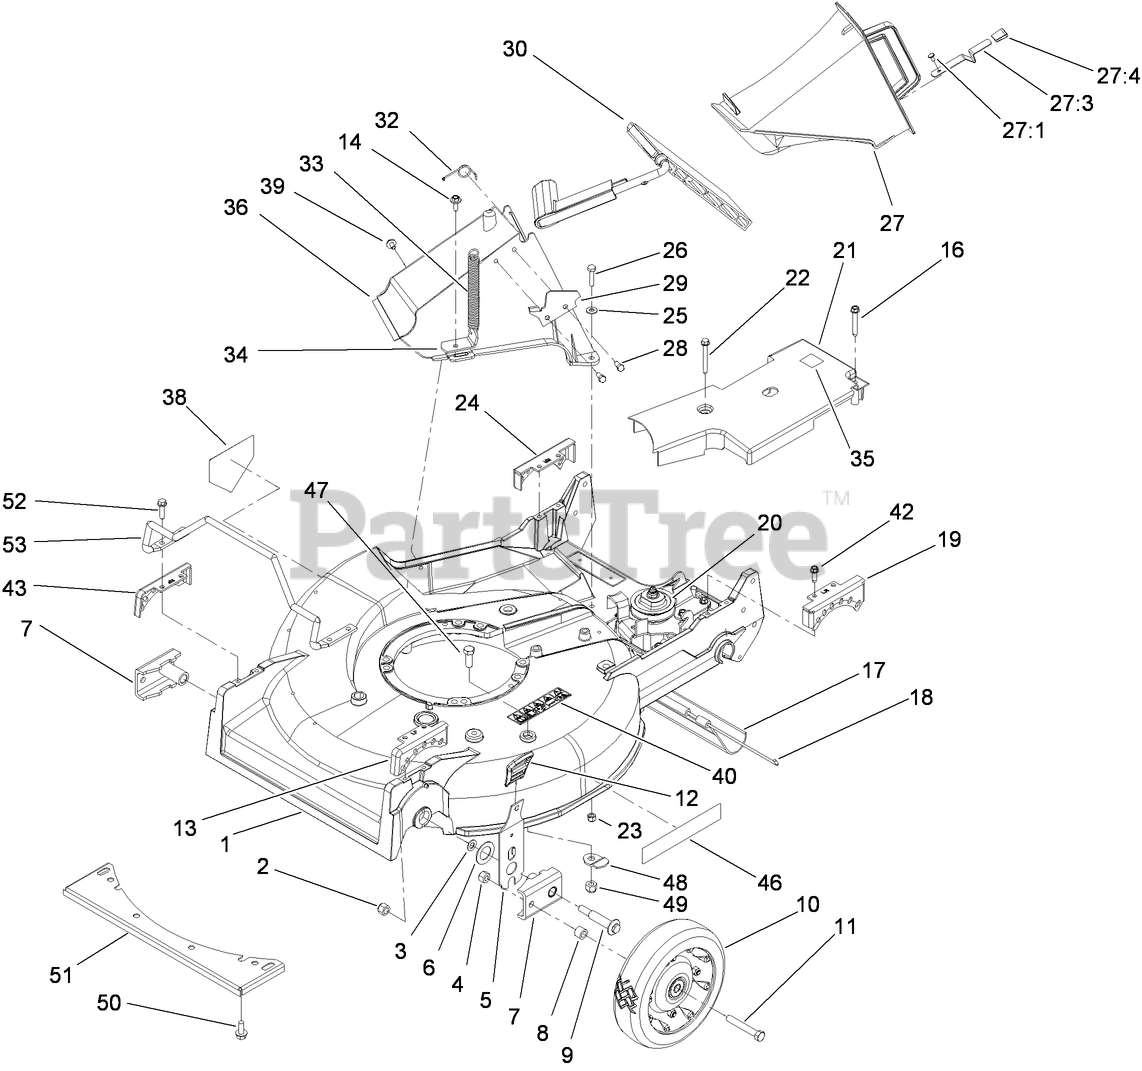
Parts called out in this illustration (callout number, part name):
1	HOUSING
2	NUT-LOCK
3	WASHER
4	NUT-LOCK, CONE
5	FRONT SPRING ARM ASM
6	WASHER-THRUST
7	ARM-PIVOT, FRONT
8	SPACER-WHEEL
9	SCREW-SHOULDER
11	SCREW-HH
12	KNOB-HOC
13	QUADRANT-FRONT, LH
14	SCREW-HWH
16	SCREW-HWHTF
17	SHIELD-TRAILING
18	ROD-SHIELD
19	QUADRANT-REAR, LH
20	GEAR CASE ASM
21	COVER-BELT
22	SCREW-HWH
23	NUT-LOCK, NI
24	QUADRANT-REAR, RH
25	WASHER-FLAT
26	SCREW-HH
27	DISCHARGE PLUG ASM
27:1	RIVET-HEAD, FLAT
27:3	LATCH-PLUG, DISCHARGE
27:4	GRIP-LATCH
28	SCREW-PLASTITE
29	LATCH-PLATE
30	DISCHARGE DOOR ASM
32	RETAINER-DOOR
33	SPRING-DOOR
34	BRACKET-SPRING
35	DECAL-GREASE
36	TUNNEL-DISCHARGE
38	DECAL-DANGER
39	SCREW AND WASHER ASM
40	DECAL-DANGER
42	SCREW-HWHTF
43	QUADRANT-FRONT, RH
47	SCREW-HH
48	SHIELD-RETAINER
49	NUT-LOCK, NI
50	SCREW-HWHTF
52	SCREW-HWHTF
53	GUARD-ENGINE
